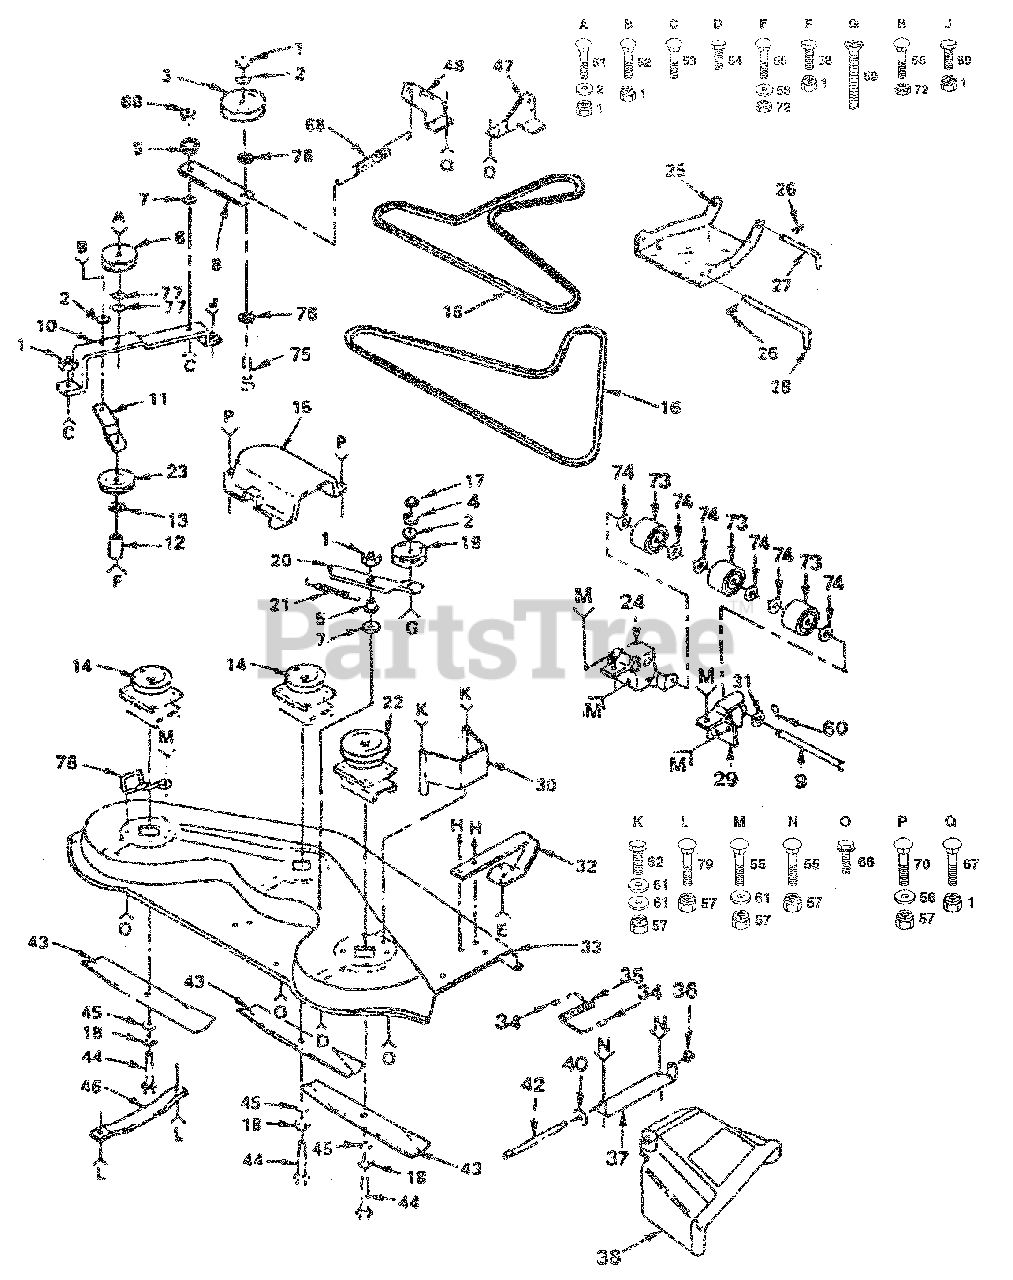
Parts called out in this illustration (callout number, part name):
1	Nut, Crownlock 3/8-16
2	Washer 13/32 x 1 x 14 Gauge
3	Pulley, Idler
4	Washer, Lock 3/8
5	Spacer
6	Pulley, Idler
7	Washer, Wear
8	Arm, Idler
9	Pin, Pivot
10	Bar, Support, Idler
11	Brace, Idler, Deck
13	Washer 13/82 x 13/16 x 16 Gauge
14	Mandrel, Secondary
16	V-Belt
17	Nut, Hex 3/8-16
18	Washer, Lock 3/8
19	idler, Flat
20	Arm, Idler, Deck
21	Spring, Extension
22	Mandrel, Primary
23	Pulley, Idler
24	Bracket, Lift, LH
25	Link, Parallel
26	Retainer, Spring
27	Pin, Front Hinge
28	Pin, Rear Hinge
29	Bracket, Lift, RH
30	Guard, Belt, RH
31	Washer 15/32 x 1 x 16 Gauge
32	Runner, RH
33	Housing, Mower
34	Cap, Sleeve
36	Nut, Push
37	Bracket, Deflector
38	Guard, Discharge
40	Washer 11/32 x 5/8 x 16 Gauge
42	Rod, Hinge
43	Blade, Mower
44	Bolt, Hex 3/8-24 x 1-1/2 Grade 5
45	Washer 13/32 x 1-1/4 x 12 Gauge
46	Runner LH
47	Bracket, Suspension Pear RH
48	Bracket, Suspension, Rear, LH
51	Bolt, Carriage 3/8-16 x 1-3/4
52	Bolt, Carriage 3/8-18x1
53	Bolt, Carriage 3/8-16 x 1 -1/2
54	Bolt, Hex 3/8-16 x 1-1/4
55	Bolt, Carriage 5/16-18 x 3/4
56	Washer 11/32 x 11/16 x 16 Gauge
57	Nut, Crownlock 5/16-18
58	Bolt, Hex 3/8-16 x 3
59	Screw, Flat Head 3/8-16 x 2
60	Pin, Cotter
61	Washer 11/32 x 3/4 x 16 Gauge
62	Bolt, Hex 5/16-18 x 5
66	Screw, Hex Washer Head, Thd., Roll. 3/8-16 x 3/4
67	Bolt, Carriage 3/8-16 x 3/4
68	Spring, Extension
69	Nut, Centerlock 3/8-16
70	Bolt, Carriage 5/16-18 x 3/4
72	Lockout 5/16-18
73	Roller, Nose
74	Washer 15/32 x 1 x 10 Gauge
75	Bolt, Carriage 3/8-16 x 2-1/2
76	Washer 13/32 x 3/4 x 10 Gauge
77	Washer 13/32 x 7/8 x 10 Gauge
78	Keeper, Mandrel, LH
79	Bolt, Carriage 5/16-18 x 5/8
80	Bolt, Fin Hex 3/8-16 x 1
